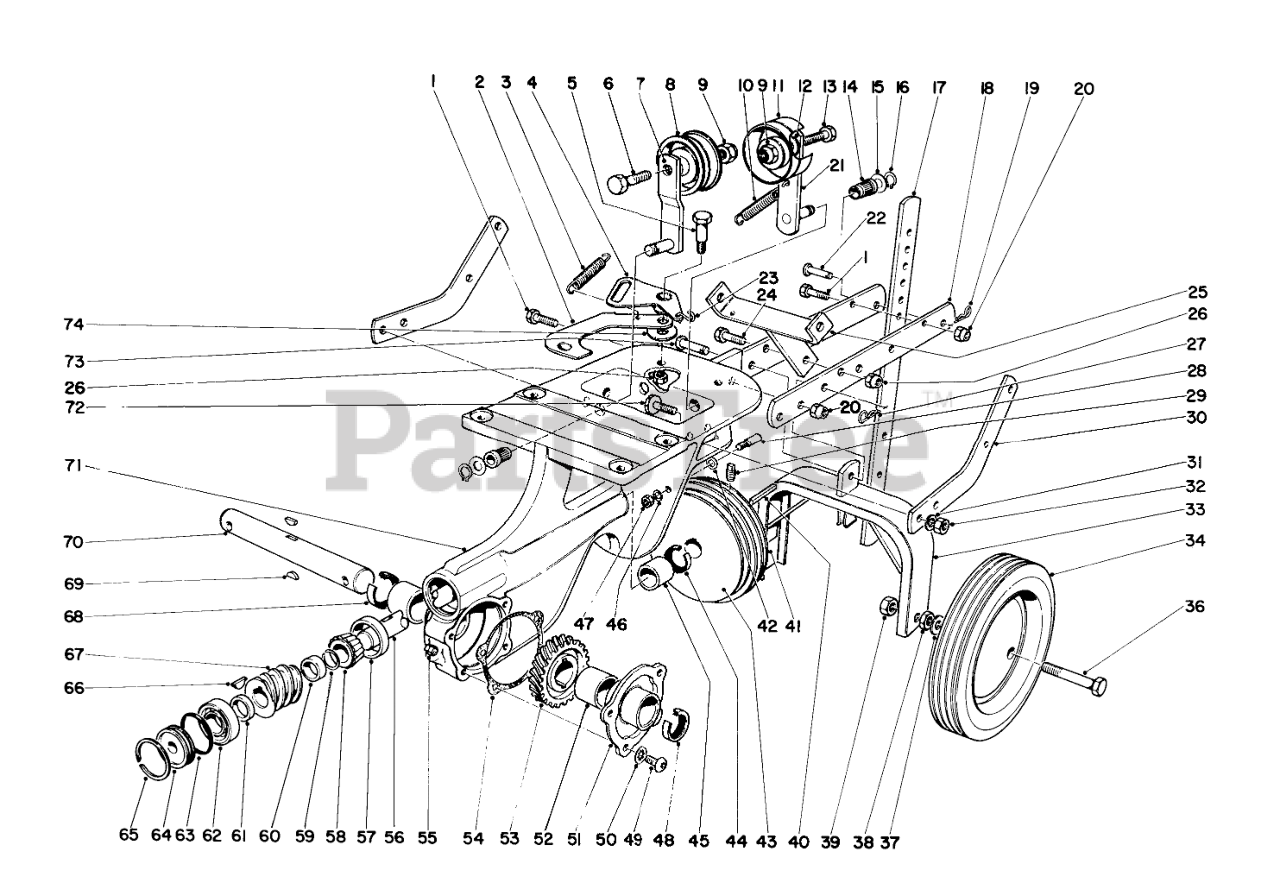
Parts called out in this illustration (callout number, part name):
1	SCREW-HH
2	Rev. Link
3	Spring
4	Bellcrank
5	SCREW-SHOULDER, HH
6	SCREW-HH
7	IdlerArm
8	PULLEY IDLER
9	NUT-LOCK, CONE
10	Spring
11	IDLER PULLEY
12	Washer
13	SCREW-HH
14	IDLER BRG
15	Washer
16	RING-RETAINING, EXT
17	DEPTH GAGE
18	Drawbar
19	PIN-COTTER, HAIR
20	NUT-LOCK, CONE
21	Idler
22	Pin
23	S Hook
24	SCREW-HH
25	Support
26	NUT-LOCK, CONE
27	PIN-COTTER, HAIR
28	Belt Guide
29	SCREW-SET, HSH
30	Handle Bracket
31	WASHER-LOCK
32	NUT-HEX
33	Wheel Bracket
34	Wheel
36	Axle
37	WASHER-FLAT
38	NUT-JAM
39	1/2-13 CONELOCK NUT
40	KEY-SQUARE
41	Pulley
42	WASHER-FLAT
43	Pulley
44	Oil Seal
45	BUSHING
46	WASHER-LOCK/EXT
47	NUT-JAM
48	SEAL-OIL
49	SCREW-HSBH
50	WASHER-LOCK
51	Cover
52	Bearing
53	WORM WHEEL
54	GASKET
55	PLUG-PIPE, SQH
56	WORM SHAFT
57	1.750 ROLLER BRG CUP
58	3/4 ROLLER BRG CONE
59	RETAINER RING
60	WORM SHF REAR SPACER
61	SPACER
62	.750 BALL BEARING
63	O-RING
65	INTRNL RETAINING RING
66	KEY-WOODRUFF
67	WORM GEAR
68	SEAL-OIL
69	Woodruff Key
70	WORM WHEEL SHAFT
71	Chassis
72	Leveler Hd.
73	Pin
74	Washer
